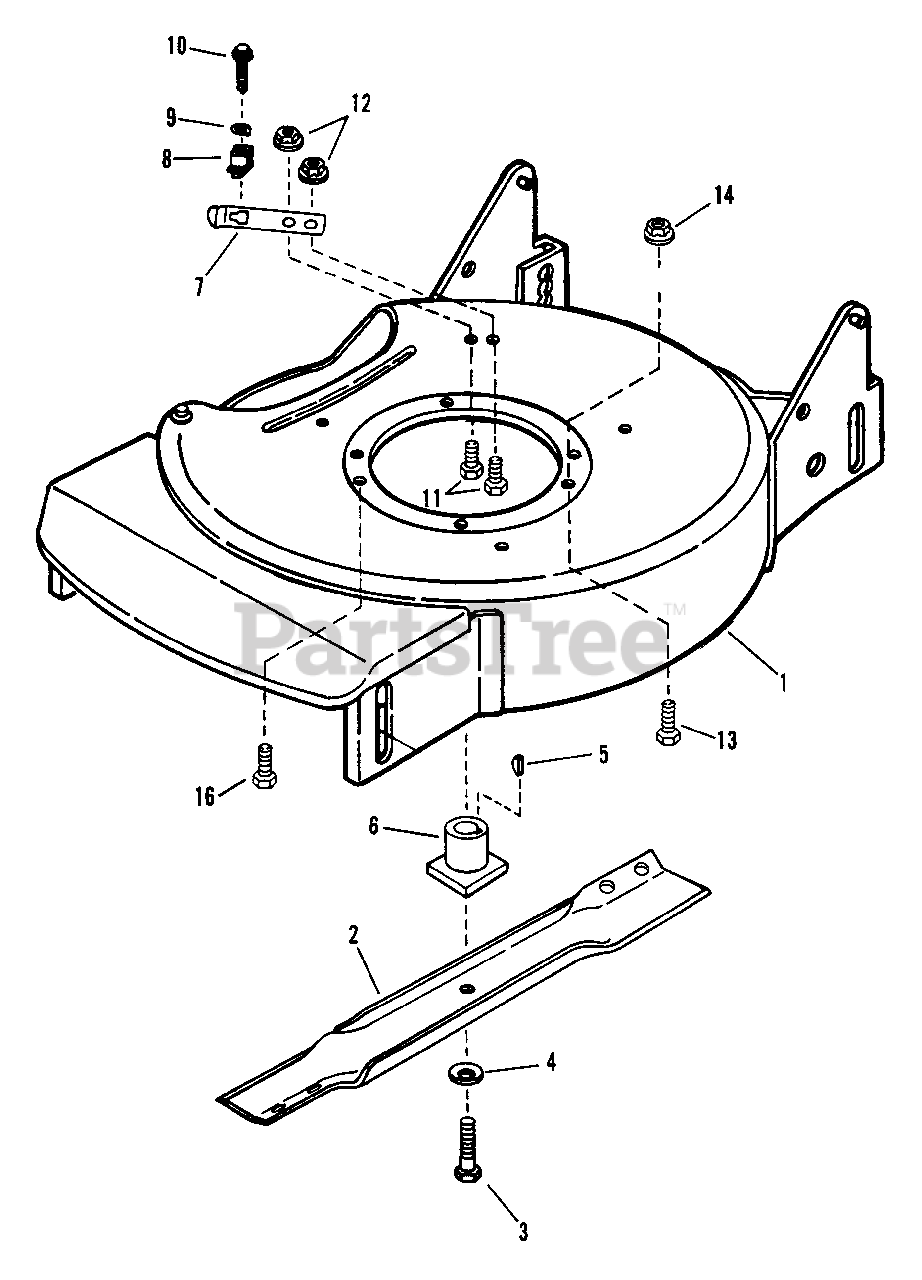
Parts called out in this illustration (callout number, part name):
1	DECK, Mower
2	BLADE, Cutter
3	SCREW, 3/8-24 x 2" Hex Head Cap (Gr. 5)
4	WASHER, Cone
5	KEY, Hi-Pro (Tecumseh 2-Cycle)
6	HUB, Blade Drive (Tecumseh 2-Cycle)
7	SPRING, Interlock
8	INSULATOR, Interlock
9	WASHER, #8 Tab
10	SCREW, #8-18 x 3/4" Self-Tapping
11	SCREW, 1/4-20 x 3/4" Hex Flange Lock
12	NUT, 1/4-20 Hex Flange
13	BOLT, 5/16-18 x 3/4" Hex Flange Lock
14	NUT, 5/16-18 Hex Flange Lock
16	SCREW, 3/8-16 x 1" Self-Tapping
